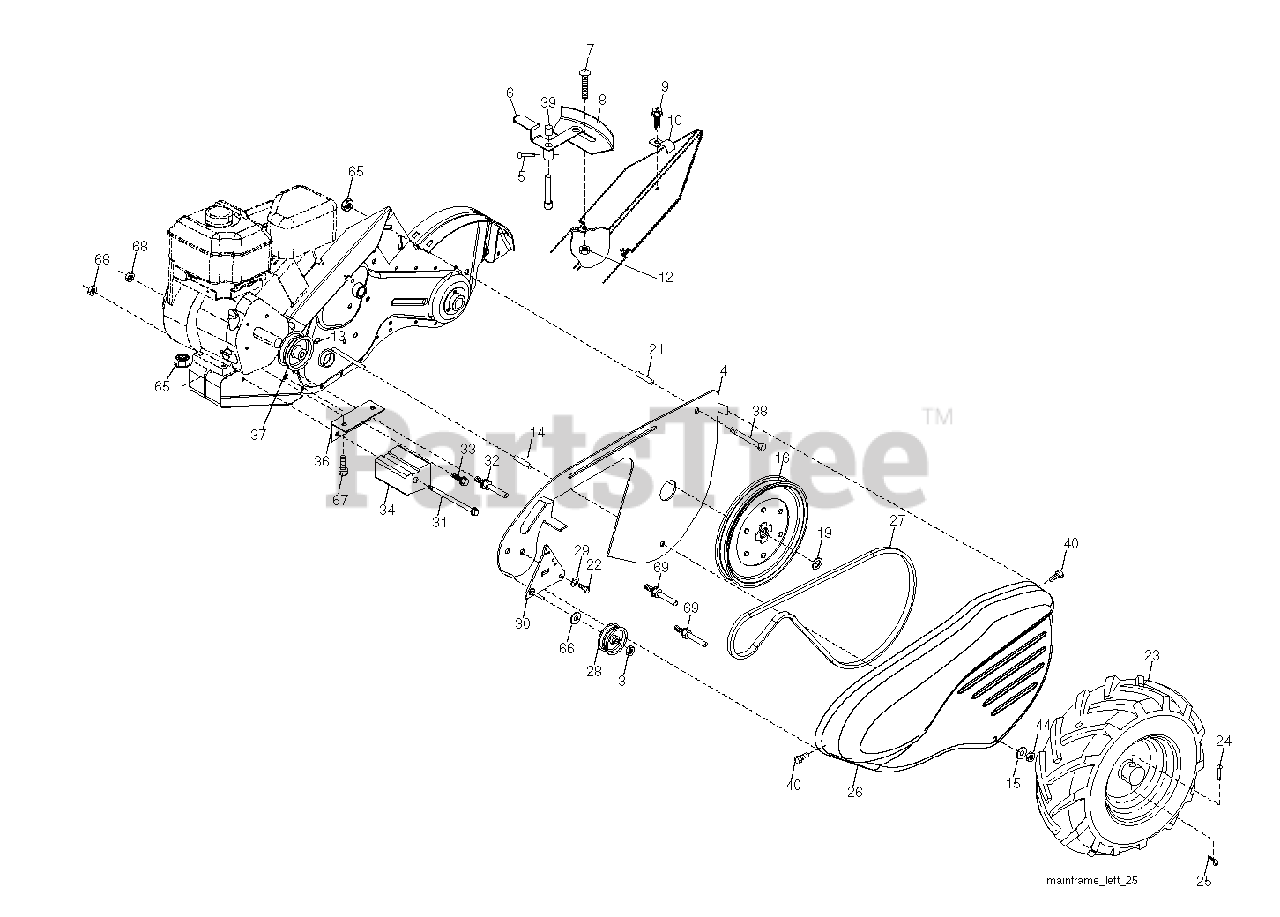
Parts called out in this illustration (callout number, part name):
3	NUT.HEX.3/8-16UNC
4	SHIELD.INNER.BELT.GUARD.RT
5	PIN.SPIROL.FLARED
6	LEVER ASM CRT
9	TAPPING SCREW
10	CONDUIT CLIP T
12	NUT
13	SET SCREW **
14	SPACER-SPLIT.327 X .42
15	WASHER
16	SHEAVE, TRANSMISSION
19	RETAINING RING LT
21	SPACER CRT
23	VALVE STEM LT
24	RIVET,DRILLED
25	RETAINER M
27	V-BELT
28	PULLEY-IDLER TI
29	KLIP RING
30	BRACKET.ASM.IDLER
31	BOLT.FIN.HEX.3/8-16UNC
32	SHIFT ARM CRT
33	BOLT
34	COUNTERWEIGHT.LH.CRT
36	BRACKET LH CRT
37	ENGINE PULLEY
38	BOLT
39	CAP.PLUNGER.BLACK
40	SCREW.HEX.WSH.SLT.#10-24X.50
44	NUT.71038.31-18.HEX.NYLOCK
65	LOCKNUT-FLANGE 5/16-18
66	WASHER
67	BOLT
69	KEEPER.BELT.ENGINE
